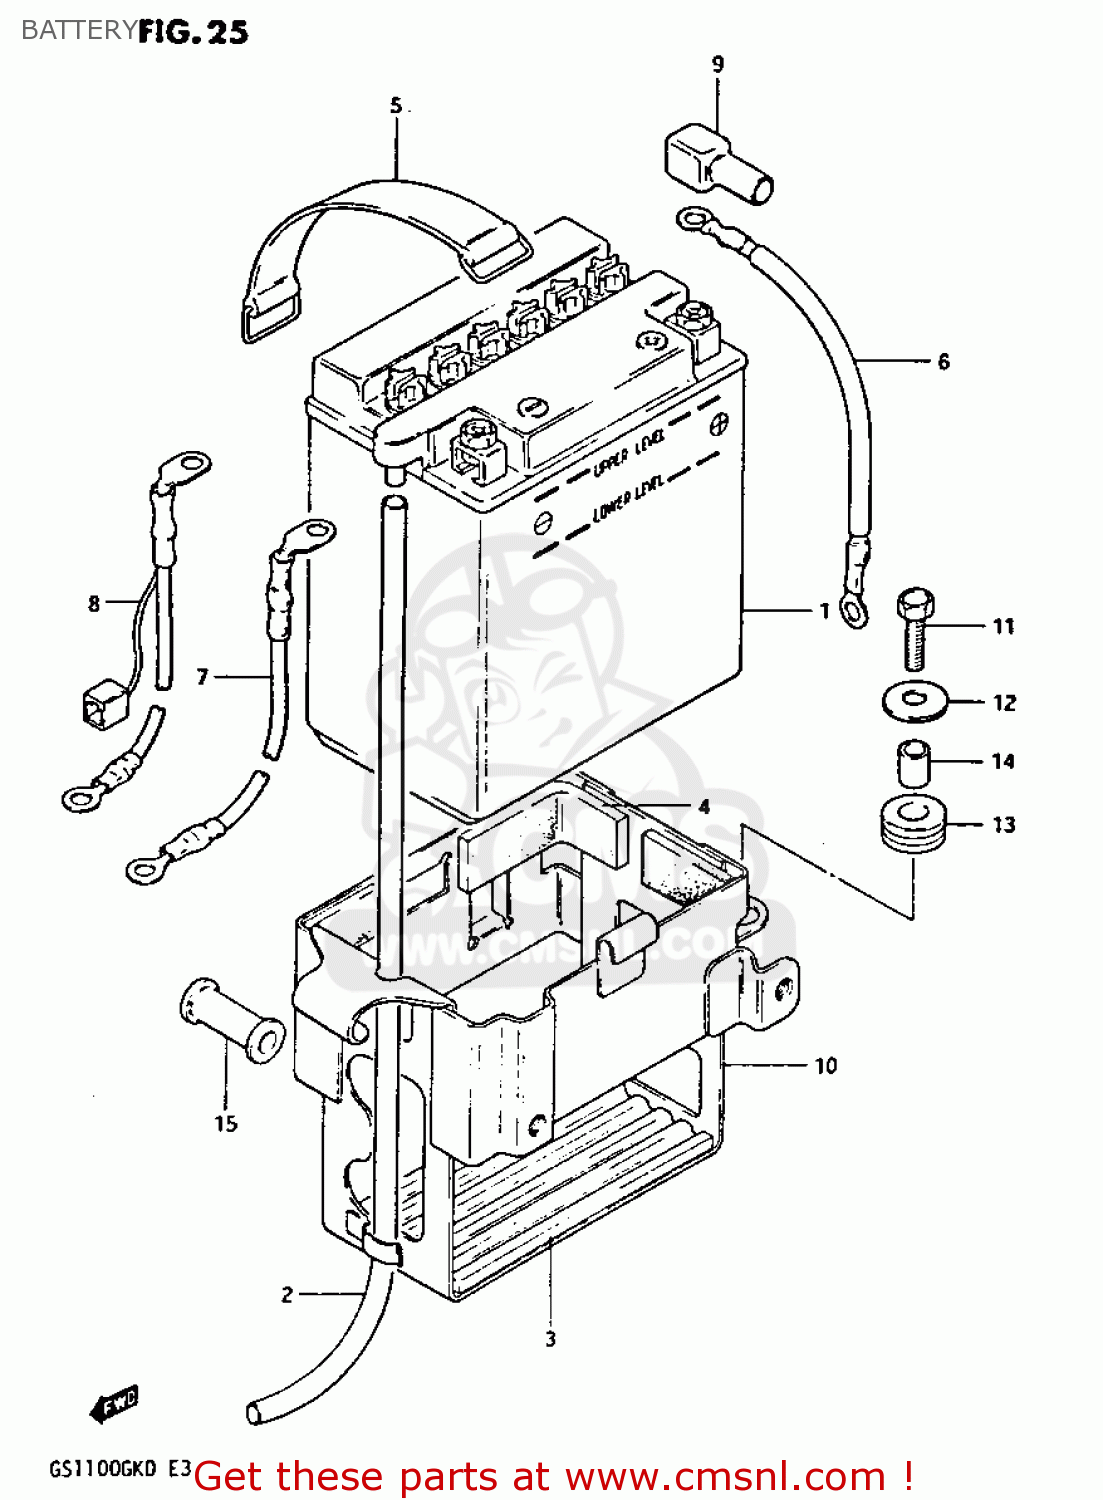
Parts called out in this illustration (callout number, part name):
1	BATTERY ASSY (12V)
2	HOSE,BATTERY EXHAUST
3	PROTECTOR,BATTERY
4	PROTECTOR(170X95X3.0)
5	BAND
6	WIRE,BATTERY PLUS
7	LEAD WIRE,BATTERY(-)
8	WIRE,BATTERY MINUS LEAD
9	CAP,TERMINAL
10	HOLDER,BATTERY
11	BOLT
12	WASHER(6,5X22X1.6)
13	CUSHION
14	SPACER(6.2X8.3X5.7)
15	CUSHION
